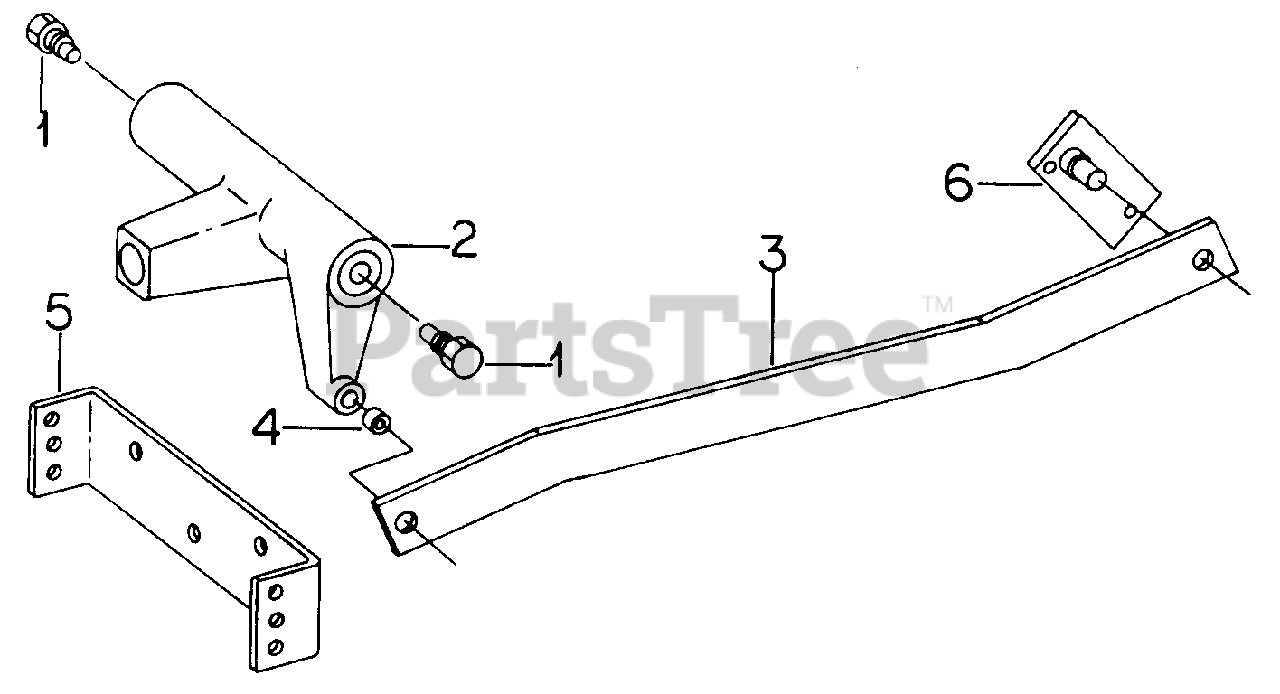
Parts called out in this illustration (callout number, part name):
1	Bolt, Stud Shaft
2	Lever, Lift
3	Bar, Lift
4	Spacer, Lift Arm
6	Plate Assy, Lift Bar
